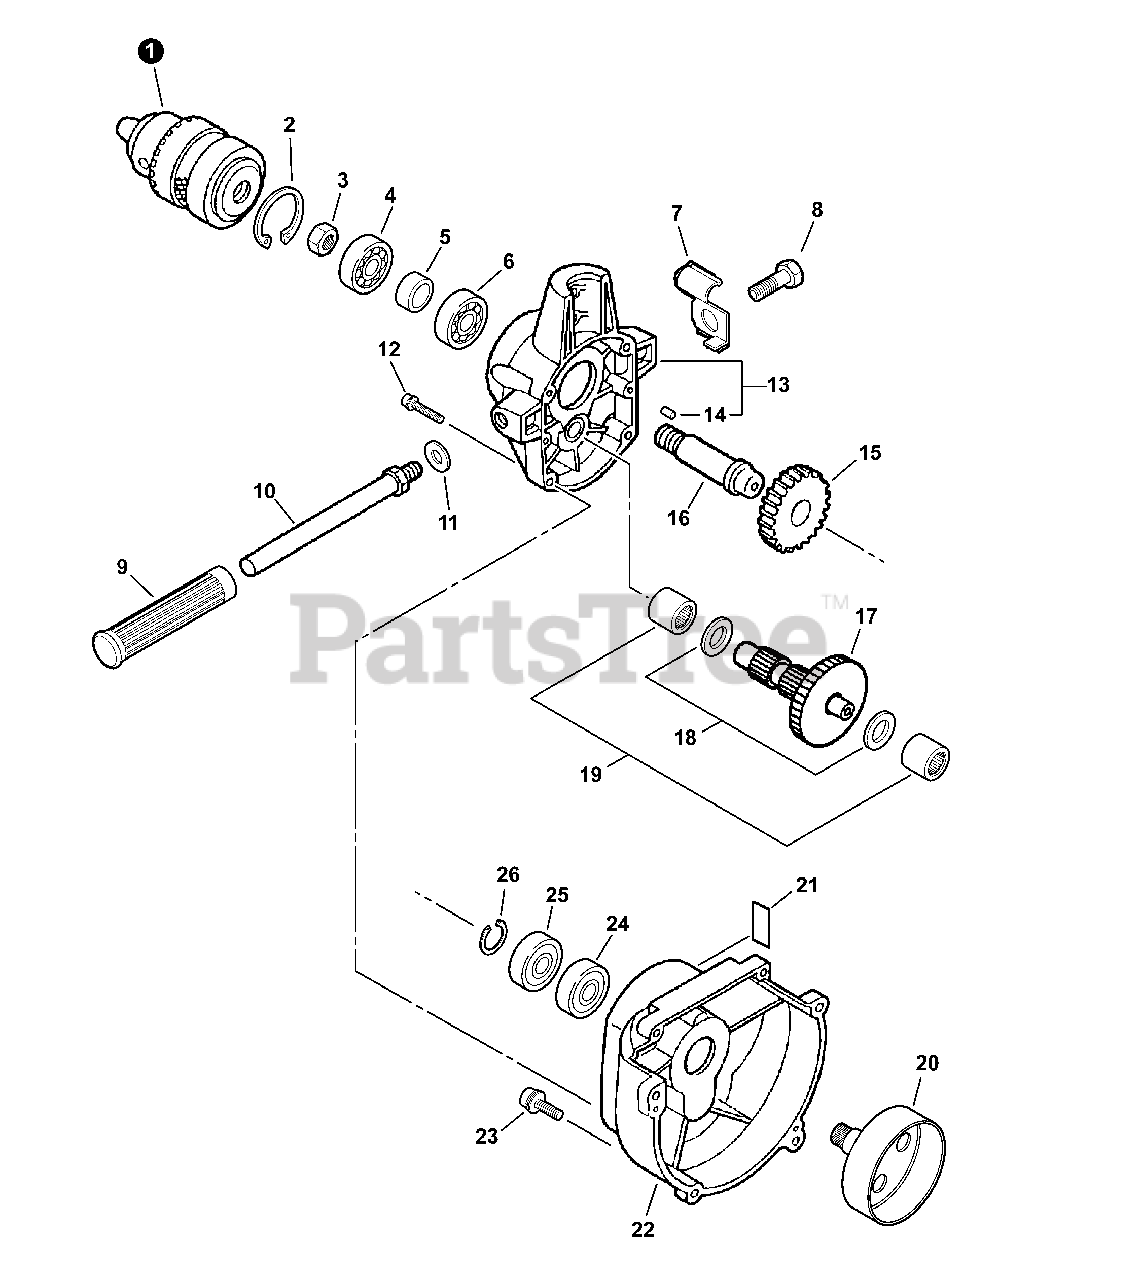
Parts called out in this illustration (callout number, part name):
1	CHUCK, KEYED
2	RING, SNAP Ø32
4	BEARING, BALL 6002 DDU
6	BEARING, BALL 6002
7	HOLDER, CHUCK KEY
8	BOLT 10×1.5×15
9	GRIP
10	HANDLE, LEFT
11	WASHER 10.5×18×1.6
12	BOLT 5×25
13	HOUSING, GEAR CASE
14	PIN, LOCATING 4×8
15	GEAR, SPUR
16	GEAR, SHAFT
17	GEAR, SHAFT
19	BEARING, NEEDLE
20	DRUM, CLUTCH
21	LABEL, CAUTION - HOT
22	COVER, FAN
23	SCREW 4×16
24	BEARING, BALL 6001
25	BEARING, BALL 6001
26	RING, RETAINING - 12
